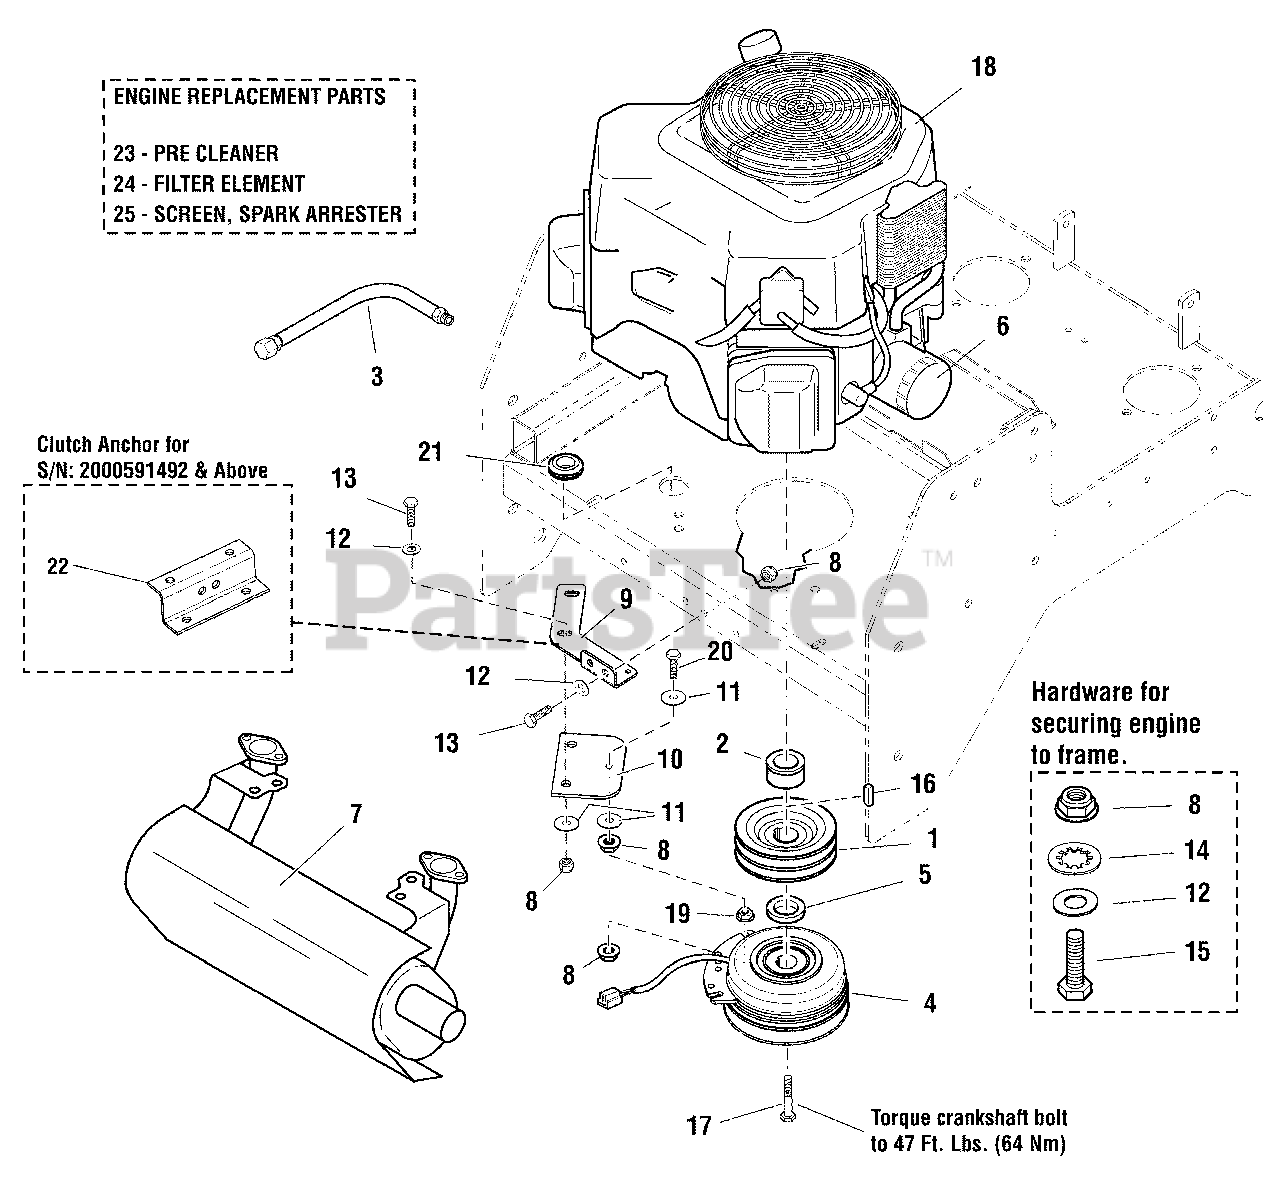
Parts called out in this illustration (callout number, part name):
1	PULLEY, CRANKSHAFT (DOUBLE A)
2	SPACER, 1.13 X 1.75 X 1.03
3	HOSE, OIL DRAIN
4	CLUTCH,5218-134, WARNER
5	SPACER, 1.13 X 1.75 X .50
6	OIL FILTER (49065-2078)
7	MUFFLER, KOHLER
8	NUT, 5/16-18 HEX NYLOCK FLANGE
9	PLATE, CLUTCH ANCHOR
10	CLUTCH ANCHOR PAD
11	WASHER, .34 X 1.25 X 10 GA
12	WASHER, 5/16 SAE
13	BOLT, 5/16-18 X 1 GD5 YZ
14	WASHER, 5/16" INT. TOOTH LOCK
15	BOLT, 5/16-18 X 1-3/4" GD5
16	KEY, 1/4" SQ. X 1
17	BOLT, CRANKSHAFT 7/16 X 2 3/4
18	ENGINE, KOHLER
19	NUT 5/16-18 HEX SERRATED FLANGE (LARGE)
20	BOLT, 5/16-18 X 2-1/4" GD5 YZ
21	GROMMET, 7/8
22	ANCHOR, CLUTCH - BLK
